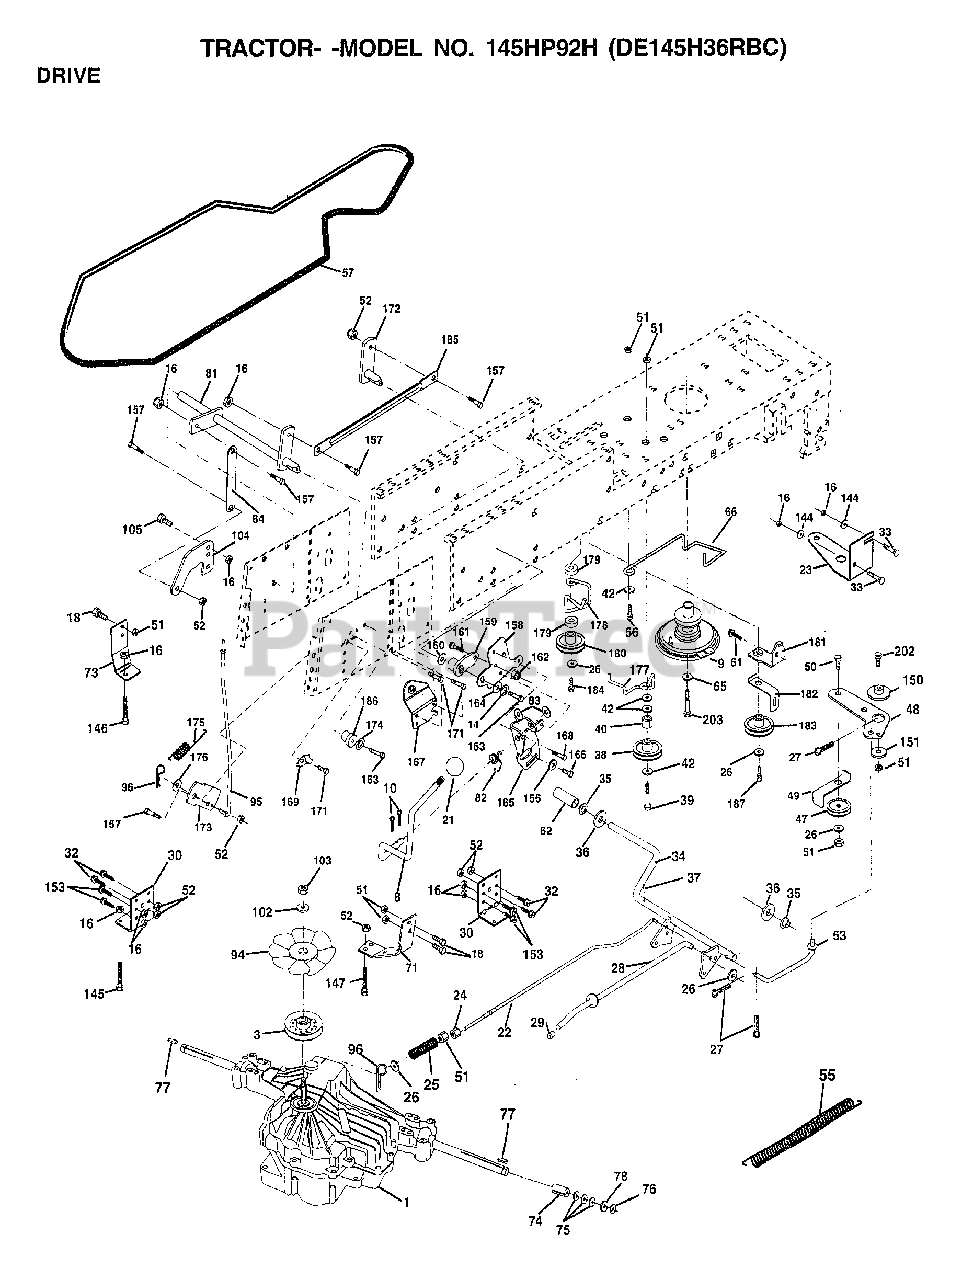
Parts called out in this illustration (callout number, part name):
3	PULLEY.TRANSAXLE
8	ROD.SHIFT.FENDER.ADJ.LT.CRD
9	CLUTCH ASM NORAM
10	PIN COTTER 1/8
14	LOCKWASHER
16	NUT
18	BOLT
21	KNOB DLX BLK/BLK
22	ROD.BRAKE.CRD
23	BRACKET CLUTCH
24	NUT
25	SPRING ROD LT
26	WASHER
27	COTTER PIN
28	ROD.BRAKE.PARK.LT
29	PLUNGER CAP T
30	BRACKET MTG TRANSAXLE
32	BOLT
33	BOLT
34	SHAFT.ASM.PEDAL.FOOT.CRD
35	NYLON BEARING
36	WASHER LT
38	PULLEY.FLAT.IDLER
39	BOLT
40	SPACER T
42	WASHER
48	BELLCRANK.CLUTCH
49	RETAIN BELT
53	"LINK, CLUTCH T"
55	"SPRING, RETURN LT"
57	"V-BELT.KEV.112"""
61	SCREW
62	PEDAL COVER T
65	LOCKWASHER
66	KEEPER-BELT
71	STRAP TORQ LH HYD
73	"STRAP-TORQUE,RH"
74	SPACER SPLIT
75	WASHER
76	E-RING LT
77	SQUARE KEY
78	WASHER
81	ASM.SHAFT
82	"SPRING,TORSION"
83	WASHER
84	LINK.TRANSAXLE
94	"FAN 7"" HYDRO"
95	CNTRL.ASM.BYPASS.HYDRO
96	RETAINER M
102	WASHER BELLEVILLE
104	ARM CONTROL HYDRO
105	SCREW CAP 5/16-18
144	WASHER
145	BOLT.HEX.FLGHD
146	BOLT.HEX.FLGHD.
147	BOLT.HEX.FLGHD
150	BUSHING.BELLCRANK.GRD.DR
151	WASHER
156	WASHER.SRRTD.5/16
157	"BOLT,SHOULDER"
158	BRKT.SHIFT.MOUNT
159	HUB.SHIFT
160	WASHER
161	BOLT T
164	WASHER.5/8X.281X10GA
165	BRKT.PIVOT.LEVER
166	SCREW.5/16-18X5/8
167	BRKT.SUPT.SHIFT.CRD
168	BOLT.SHOULDER.5/16-18X.561
169	PLATE.FASTENING
171	SCREW LT
172	LINK.SHAFT.CRD.HYDRO
173	BKRT.HYDRO.BYPASS.CRD
175	SPRING.BYPASS.CRD
176	WASHER
177	KEEPOER.FLAT.IDLER
178	KEEPER.BELT.IDLER
179	WASHER
180	PULLEY.FLAT
181	BRKT.IDLER.GRD.DR.CRD
182	"KEEPER.BELT.2.5"".OD.CRD"
183	PULLEY.V-IDLER
184	SCREW.HXWSH.3/8
185	SHAFT.ASM.SHIFTER.FRT.CRD
186	HUB.TAPERED.ROUND.CRD
187	SCREW
202	BOLT.3/8-16X1.50
203	BOLT HEX
